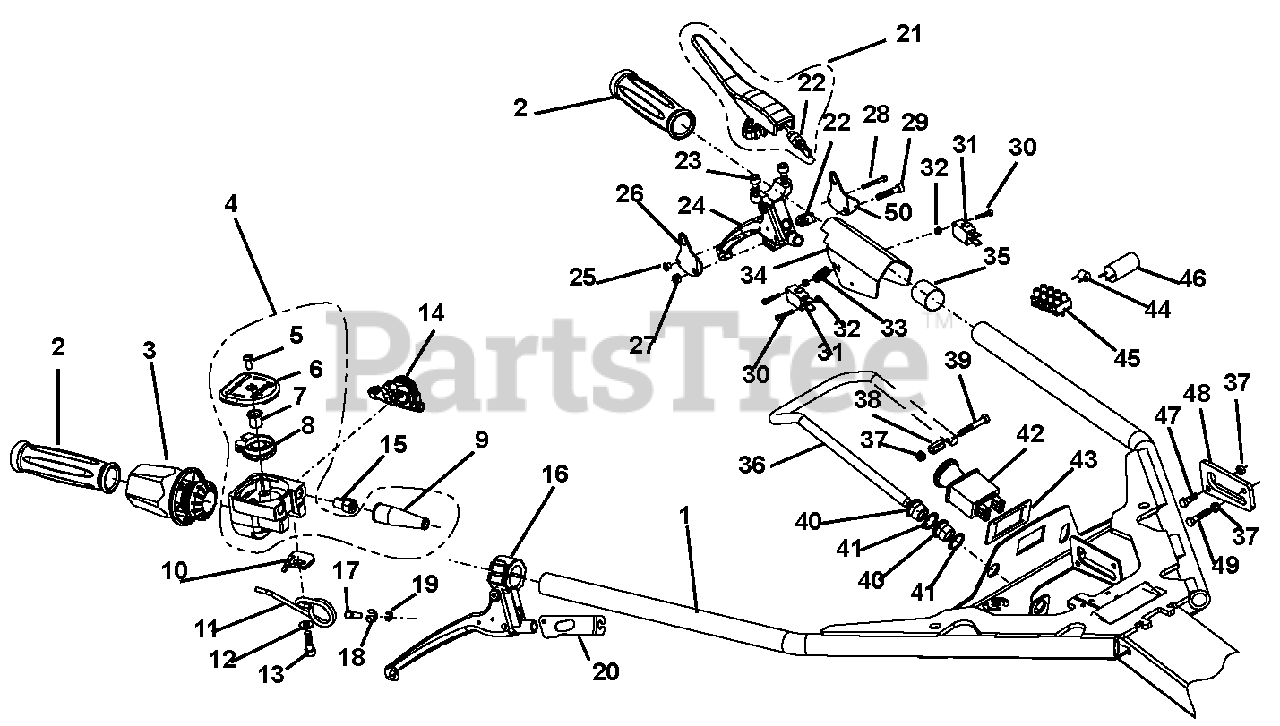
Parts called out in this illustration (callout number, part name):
1	Swiveling Handlebar
2	Rubber, Handle
3	Bushing, Grip
4	MF Control Unit CPL, (Includes items 5 - 8)
5	Screw, M5 x 12/ 10.9
7	Bushing
8	Bevel Wheel with Cam
10	Cover, Stop
11	Spring, Return
12	Spacer, 1.03 x 1.38 x .184
13	Screw, M6 x 20
14	Assembly, Throttle Lever
15	Nipple, Screwed
16	CPL, Lever
17	Bolt
18	Lockwasher, D6799 6 MM
19	Washer, Lock
21	Lever, Emergency
23	Screw, D912 M6 x 22
24	Lever, Control
26	Tracer Plate
27	Nut, Lock
28	Screw, D912 M3 x 25
29	Screw, D912 M5 x 25
30	Screw, D912 M3 x 16
31	Switch, Micro
32	Nut, Lock D985 M3
33	Tension Spring
35	Shrinkdown Tubing, RNF100 1 TYP1
36	Lever, Locking
37	Nut, Lock
38	Nut, Hex DIN 6334 M5 x 15
39	Bolt, Hex D933 M5 x 35
42	Switch, PTO
43	Front Screen
45	Clamping Ledge
46	Condenser
47	Bolt, Hex D933 M5 x 16
48	Guide Sheet Metal
49	Bolt, Hex D933 M5 x 25
50	Tracer Plate
